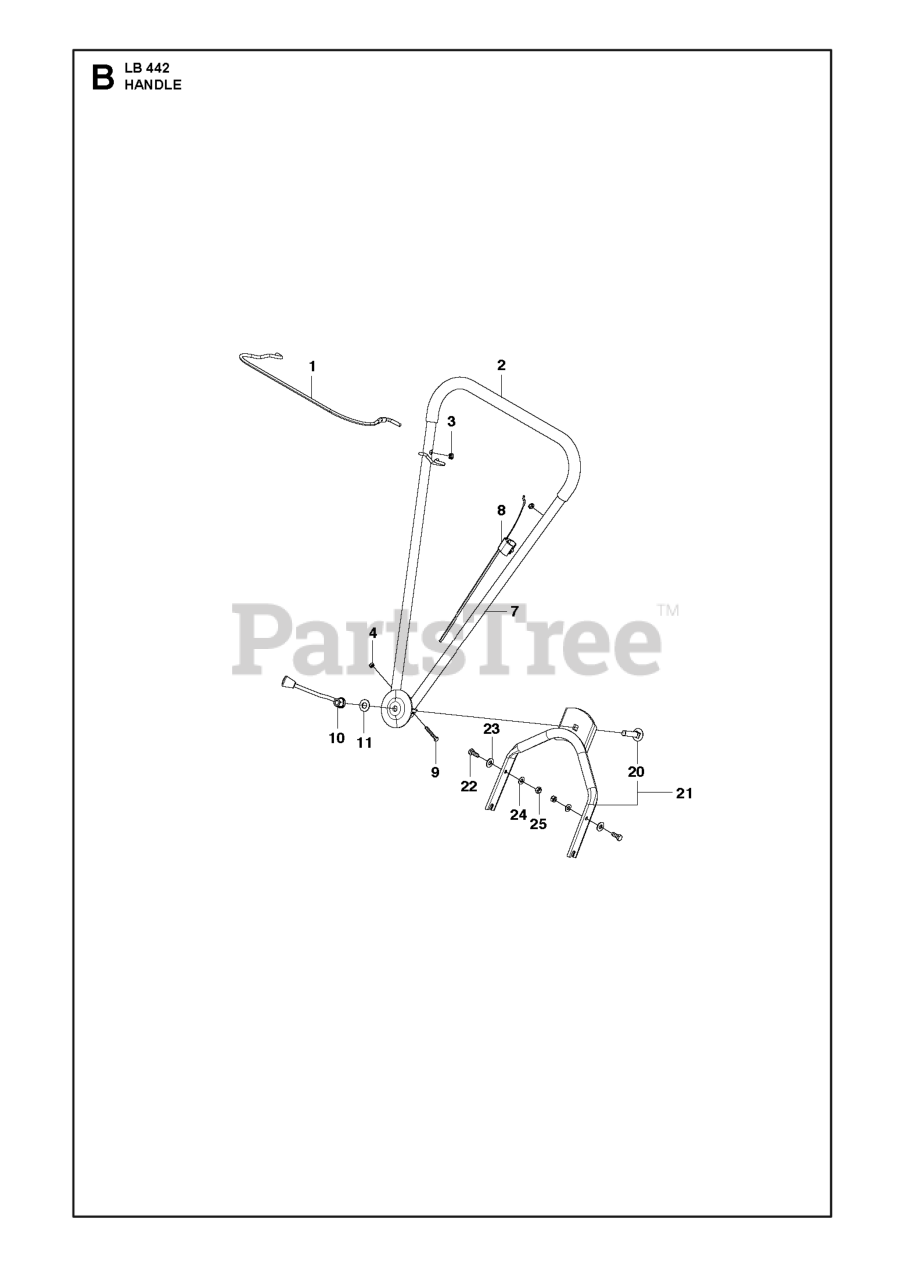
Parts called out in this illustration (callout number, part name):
4	NUT FLANGE - M6
9	Hex Head Capscrew, M6 X 1.00 X 40MM
25	NUT LOCK - M8, NYLOCK
